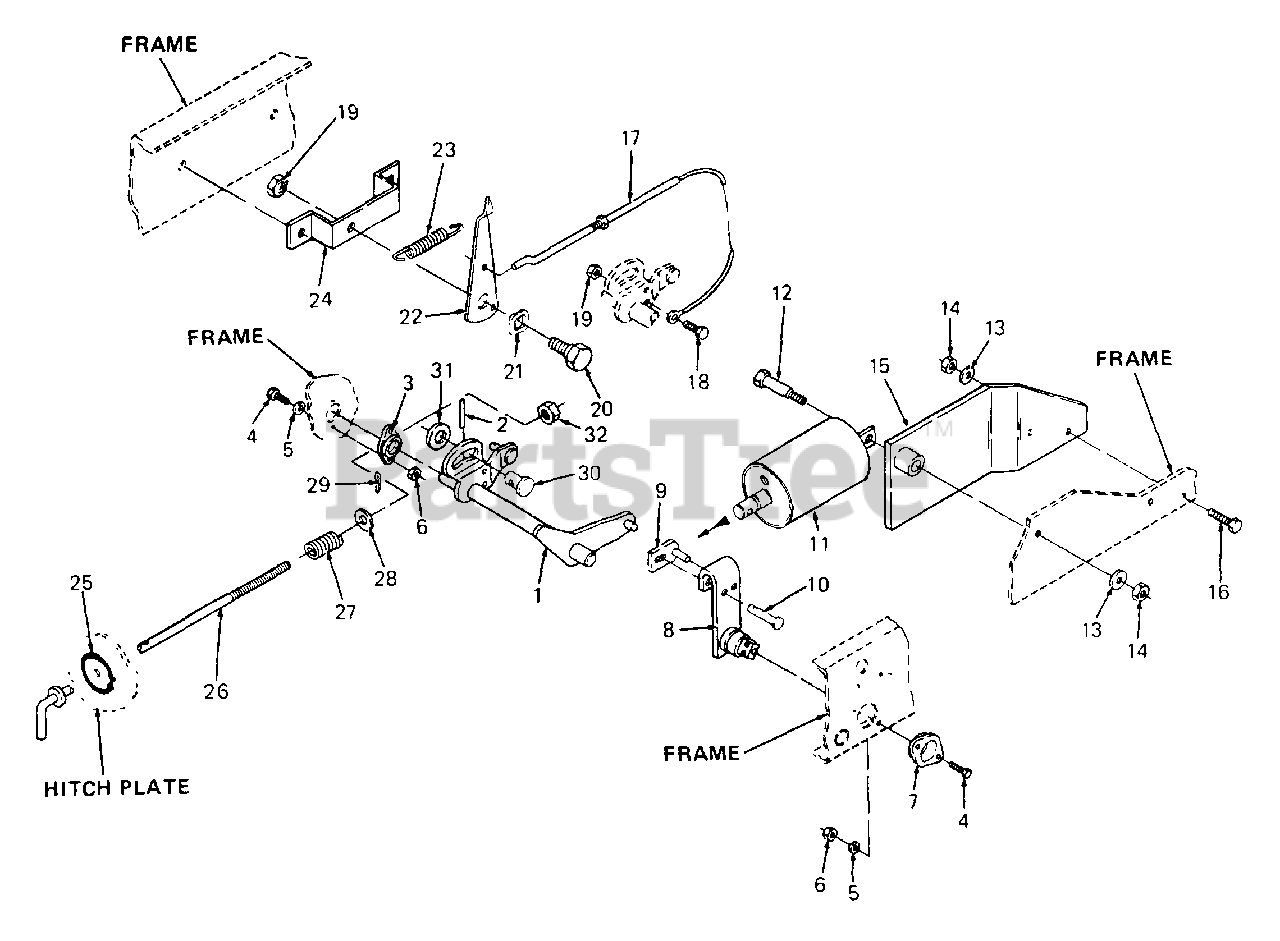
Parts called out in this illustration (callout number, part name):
3	Bushing, lift, LH
4	Screw, Hex Cap, 1/4-20 x .75 Lg GR5
5	Washer, Lock, 1/4
6	Nut, Hex, 1/4-20 GR5
7	Bushing, Lift, RH
8	Bracket Assy, Lift
9	Pin Assy, Lift
10	Pin, Clevis, 1/2 Dia x 2.172 Lg
11	Cylinder, Hydraulic
12	Bolt, Shoulder
13	Washer, Flat, .531 x 1.06 x .134 Thk
14	Nut, Hex Center Lock, 1/2-13 GR5
15	Bracket, Cylinder
16	Screw, Hex Cap, 1/2-13 x 1.25 Lg GR5
17	Cable Assy, Indicator
18	Screw, Hex Cap, 1/4-20 x .88 Lg
19	Nut, Hex Patch Lock, 1/4-20
20	Screw, Shoulder, .375 Dia x .181
21	Washer, Bowed Spring
22	Arm, Indicator
23	Spring, Extension, .33 OD x 1.12 Lg
24	Bracket, Mounting
25	Graphic, Down Stop Adjustment
26	Rod, Down Stop Adjustment
27	Spring, Compression, .501 x .75 x 1.00 Lg
28	Washer, Flat, .656 x 1.312 x .074 Thk
29	Pin, Internal Cotter
30	Clevis, .750 x 1.00 Lg
31	Washer, Flat, .758 x 2.0 x .030 Thk
32	Nut, Hex LH Thrd, 1/4-28
